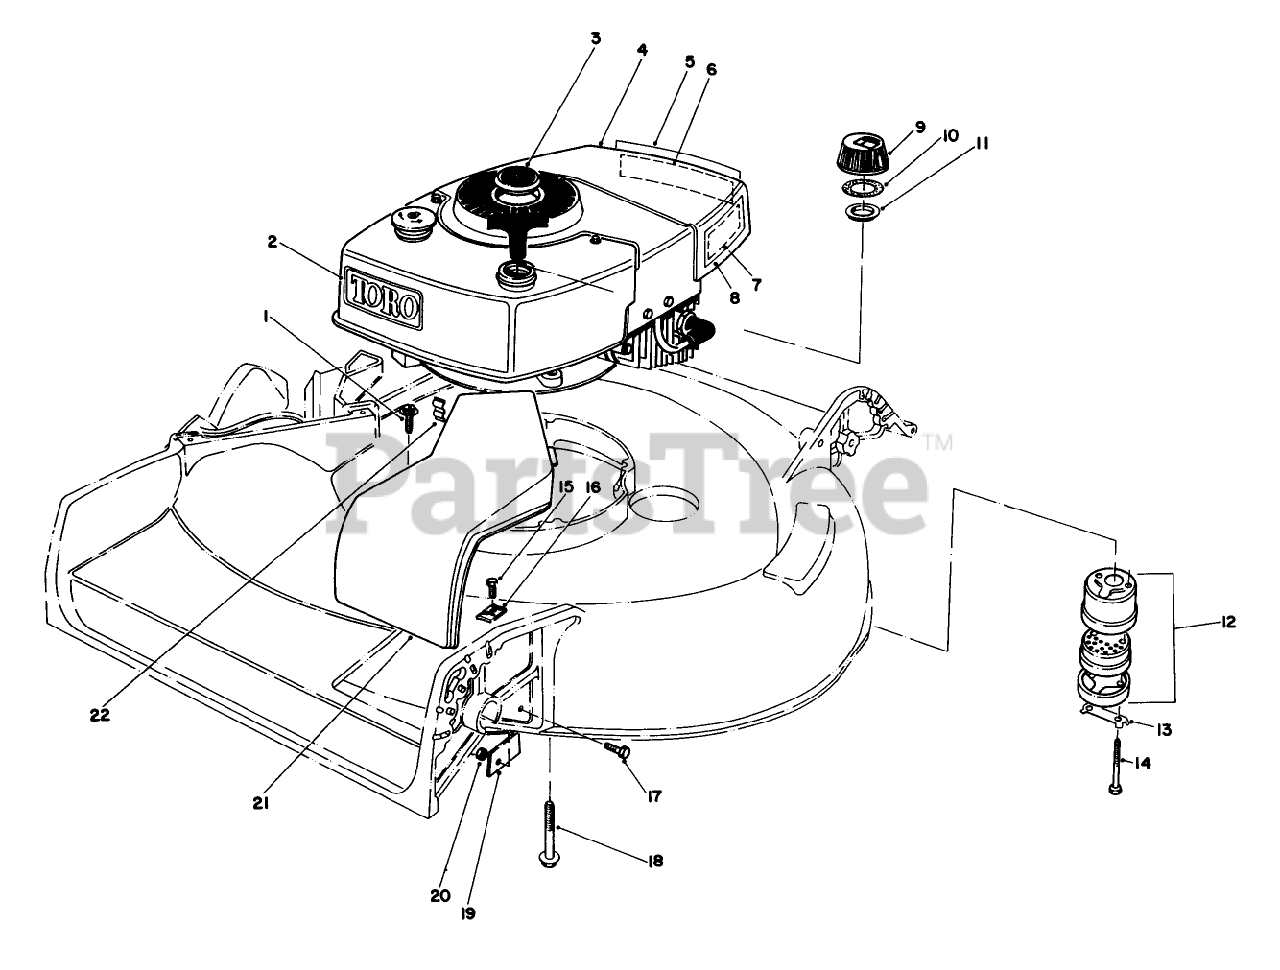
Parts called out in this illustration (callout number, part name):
1	SCREW
4	Engine
10	GASKET
12	Muffler (Incl. Ref. #10 11)
13	CLIP - LOCKING
14	SCREW-HH
15	SCREW-THD ROLL, HWH
17	SCREW-HH
18	3/8-16 X 2-3/4 CAPSCR
21	Cover-Belt Drive
